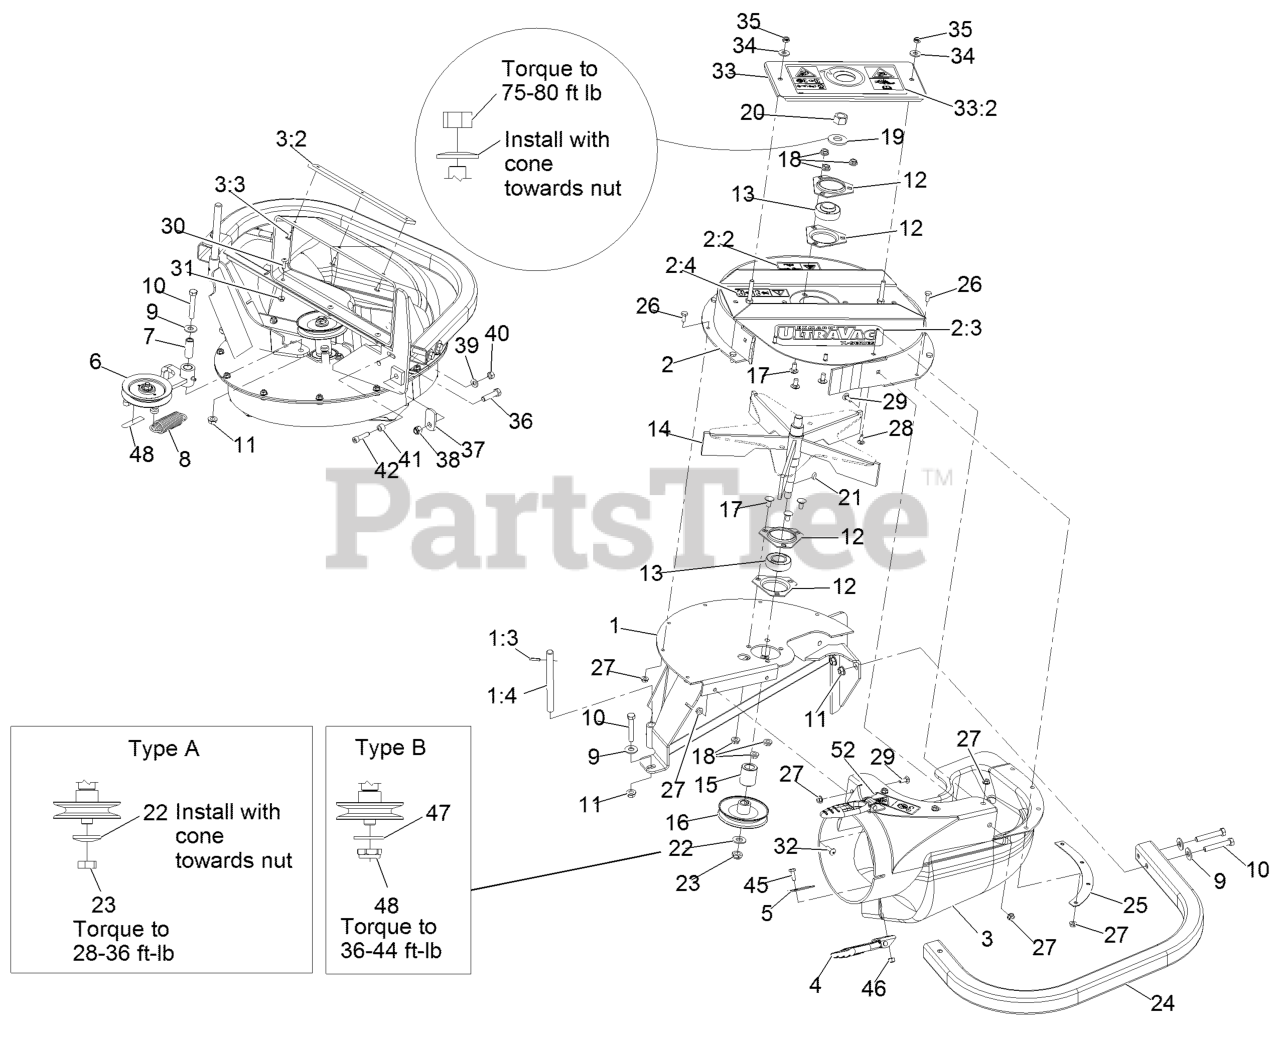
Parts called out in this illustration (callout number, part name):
1	WLD,FRAME LG BLOWER
1:3	PIN-ROLL
1:4	SHAFT-CATCHER, GRASS
2	ASM-UPPER HOUSING LARGE
2:2	DECAL-WARNING, TRACTION
2:3	DECAL-ULTRA VAC X-SERIES
2:4	DECAL-COVER, MISSING
3	ASM,BLOWER CHUTE LZ
3:2	PLATE,REINFORCEMENT LARGE
3:3	RIVET-BLIND
4	LATCH-RUBBER
5	PLATE-BACKING
6	ASM, Idler
7	BUSHING
8	SPRING-IDLER
9	WASHER-FLAT
10	SCREW-HH
11	NUT-HHF, WHIZ
12	HOUSING-FLANGE
13	BEARING
14	IMPELLER
16	SHEAVE
17	SCREW-CARR
19	WASHER-SPRING
20	NUT-HEX
21	KEY-WOODRUFF
22	WASHER-FLAT
23	NUT-LOCK, NI
25	PLATE-BACKING, BLOWER
26	SCREW-HH
28	SCREW-CARR
29	BOLT-CARR
30	SCREW-HEAD, TRUSS
33	ASM, BEARING COVER
33:2	Decal-Warning
34	WASHER-FLAT
35	NUT-LOCK, NI
36	SCREW-HH
37	LATCH-CATCHER, GRASS
38	NUT-LOCK, NI
39	WASHER-SPRING
40	NUT-HEX
41	BUSHING, LOCATOR
42	SCREW-HSH
45	SCREW-HH
46	NUT-LOCK, NI
47	WASHER-FLAT
48	NUT-LOCK, NI
52	Decal-Blower-Impeller Hazard
